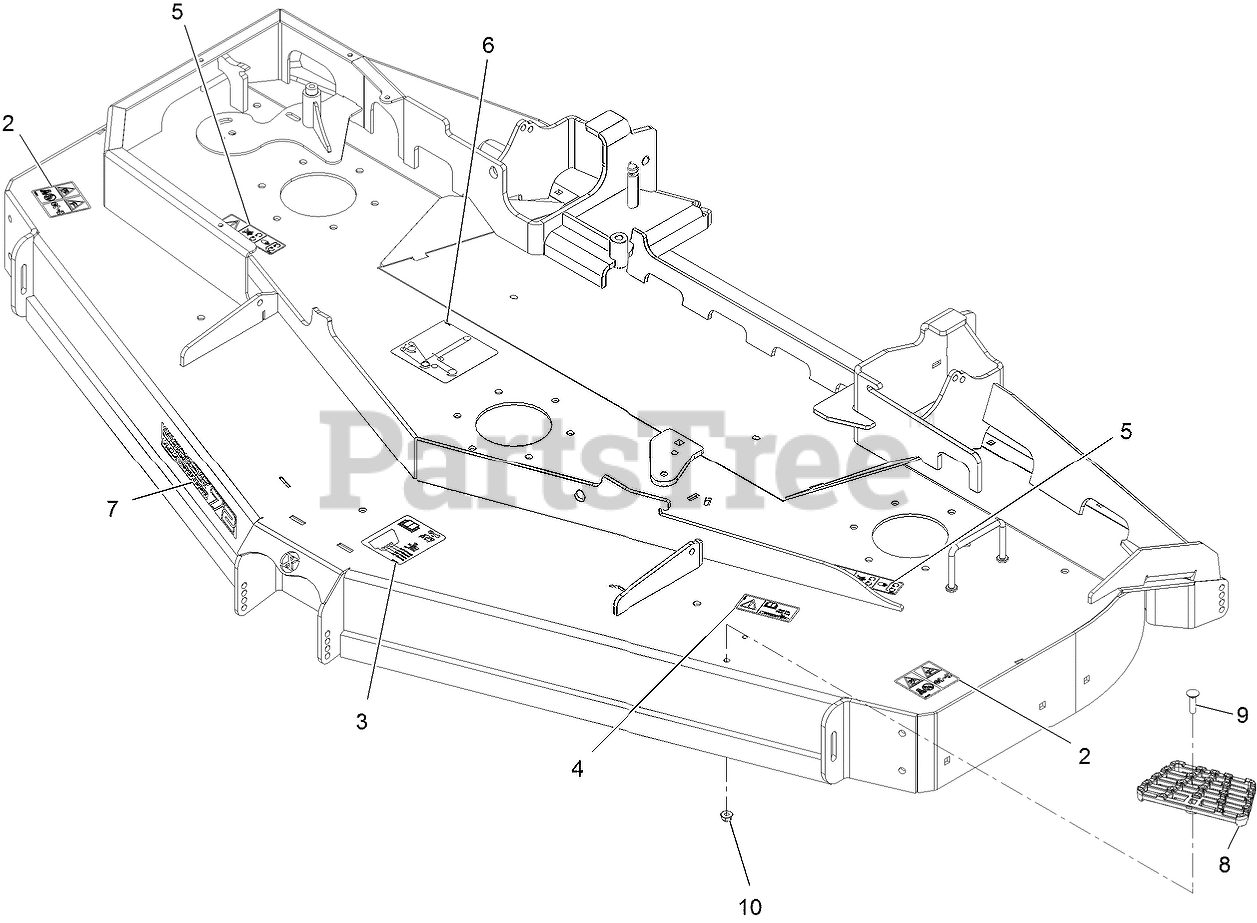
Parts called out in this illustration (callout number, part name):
2	DECAL-DANGER, THROWN OBJECT
3	DECAL-ROLLER, ANTI-SCALP
4	DECAL-TORQUE, BOLT
5	DECAL-COVER, MISSING
6	DECAL-ROUTING, BELT
7	Decal, 72Rd
8	STEP-DECK
9	Bolt-Carriage 5/16-18 X 1 1/4
10	NUT-HF, NI
